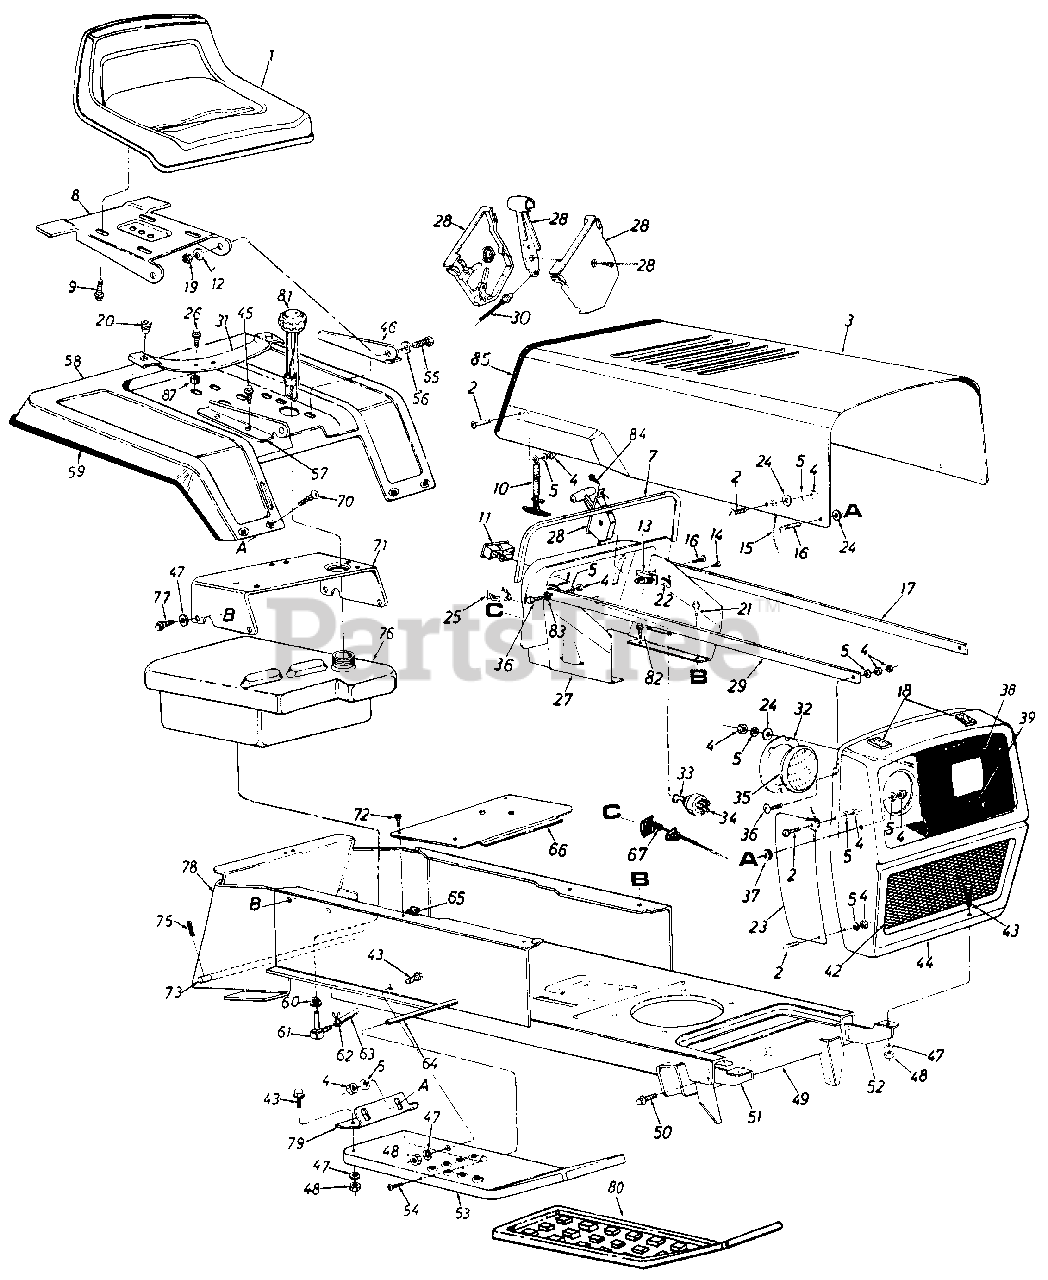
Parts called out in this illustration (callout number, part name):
1	Seat Assembly
2	Truss Mach. Scr. 1/4-20 x .50" Lg. *
5	L-Wash. 1/4" Scr.*
7	Vinyl Molding Strip-29"
8	Seat Pivot Bracket
9	Hex Wash. AD AB-Tap Scr. 3/8 x .75" Lg.
10	Hood Latch Ass'y.
11	Ammeter
12	Bell-Wash 34" I.D. x .88" 0. D.
13	Circuit Breaker 8 Amp.
14	Hex Tap Scr. #10 x .50" Lg.*
15	Hood Stop
16	Truss Mach. Scr. 1/4-20 x .75" Lg.*
17	Grille Positioning Rod
18	PVC Foam Strip 1/2 x 1.OO" x 2.00" Lg.
19	Hex Cent. L-Nut 5/16-18 Thd.
20	Grommet
21	Hex Thd. Rolling Scr. 1/4" x .50" Lg.
22	Speed Nut #10Z
23	Grille Side Panel-R.H.
24	Fl-Wash. 1/4" I.D.
25	Light Switch
26	Hex Wash. Hd. Self-Tap Scr. 5/16-18 x 1.25" Lg.
27	Dash Panel Ass'y.
28	Throttle Control Box Comp.
29	Grille Positioning Rod
30	Throttle Control Wire
31	Seat Spring
32	Head Lamp Retainer
33	Ignition Key
34	Ignition Switch
35	Head Lamp
36	Truss Machine Scr. 1/4-20 x .75" Lg.
37	Rubber Wash. .50" I.D. x 1.00 O.D. x .25 Thk.
38	Headlight Bezel
39	Hex Wash. Hd. Scr. #8-32 x .38" Lg.
42	Grille Screen
43	Hex Scr. 5/16-18 x .75" Lg.*
44	Grille Ass'y.
45	Hex Wash. Hd. Self-Tap Scr. 5/16-18 x .50" Lg.
46	Seat Brkt.-L.H.
47	L-Wash. 5/16" Scr.*
48	Hex Nut 5/16-18 Thd.
49	Lower Frame Ass'y.
50	Hex Thd. Rolling AB Scr. 5/16 x .75" Lg.
51	Grille Mount Brkt.-R.H.
52	Grille Mount Brkt.-L.H.
53	Running Board-R.H.
54	Truss Mach. Scr. 5/16-18 x .75" Lg.
55	Hex Bolt 5/16-18 x .75" Lg.
56	Bell-Wash. .34" I.D. x .88" O.D.
57	Seat Brkt.-R.H.
60	Bushing
61	90ø Nipple
62	Hose Clamp
63	Gas Line 46" Lg.
64	Running Board Rod
65	Speed Nut
66	Transmission Cover
67	Choke Control Comp.
70	Carriage Bolt 1/4-20 x .50" Lg.
71	Seat Mounting Channel
72	B-Tap Scr. #10 x .50" Lg.
73	Hitch Rod
75	Internal Cotter Pin
76	Gas Tank
77	Hex Wash. Hd. AB-Tap Scr. 3/8 x .75" Lg.
78	Hitch Plate
81	Gas Gauge
82	Hex Thd. Rolling Scr. 5/16-24 x .75" Lg.
83	External Wash. 1/4" I.D.
84	Truss. Mach. Scr. #10 x .5" Lg.
85	Trim strip-30" Lg.
87	Spacer
